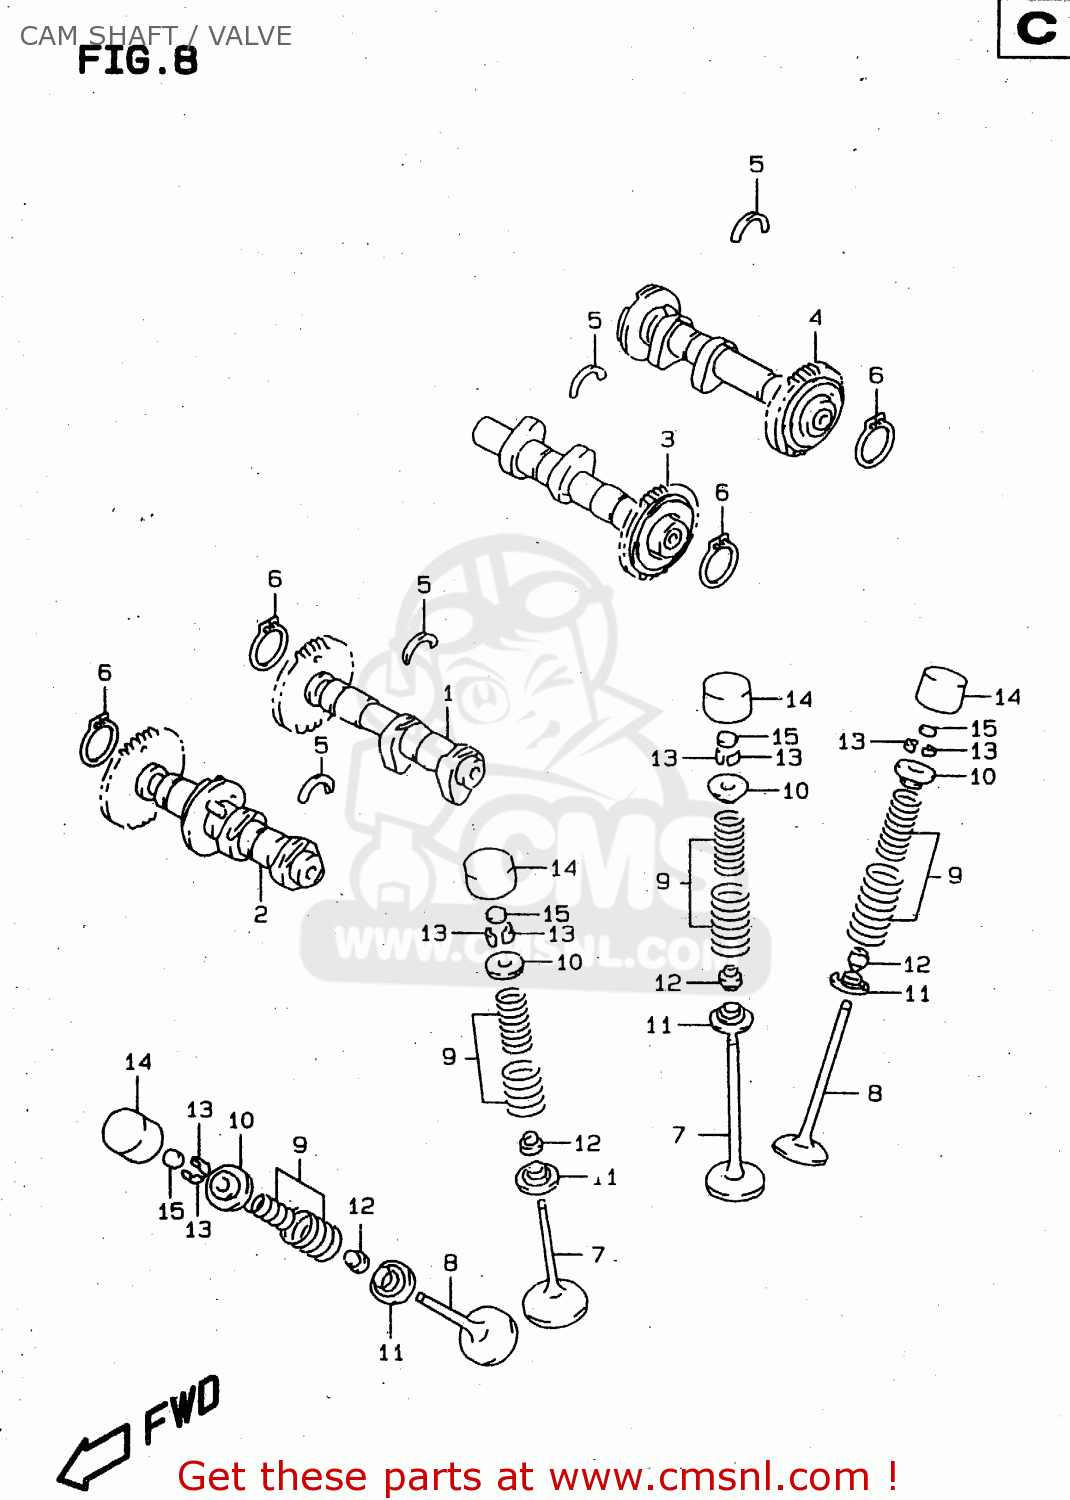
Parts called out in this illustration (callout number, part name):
1	CAMSHAFT ASSEMBLY,INTAKE,FRONT
2	CAMSHAFT ASSY,EXHAUST FR
3	CAMSHAFT ASSY,INTAKE RR
4	CAMSHAFT ASSY,EXHAUST RR
5	C RING
6	CIRCLIP
7	VALVE,INTAKE
8	VALVE,EXHAUST
9	SPRING SET,VALVE
10	RETAINER,VALVE SPRING
11	SEAT,VALVE SPRING
12	SEAL,OIL(5.5X11X8.2)
13	COTTER,VALVE
14	TAPPET
15	SHIM,TAPPET(T:2.3)
